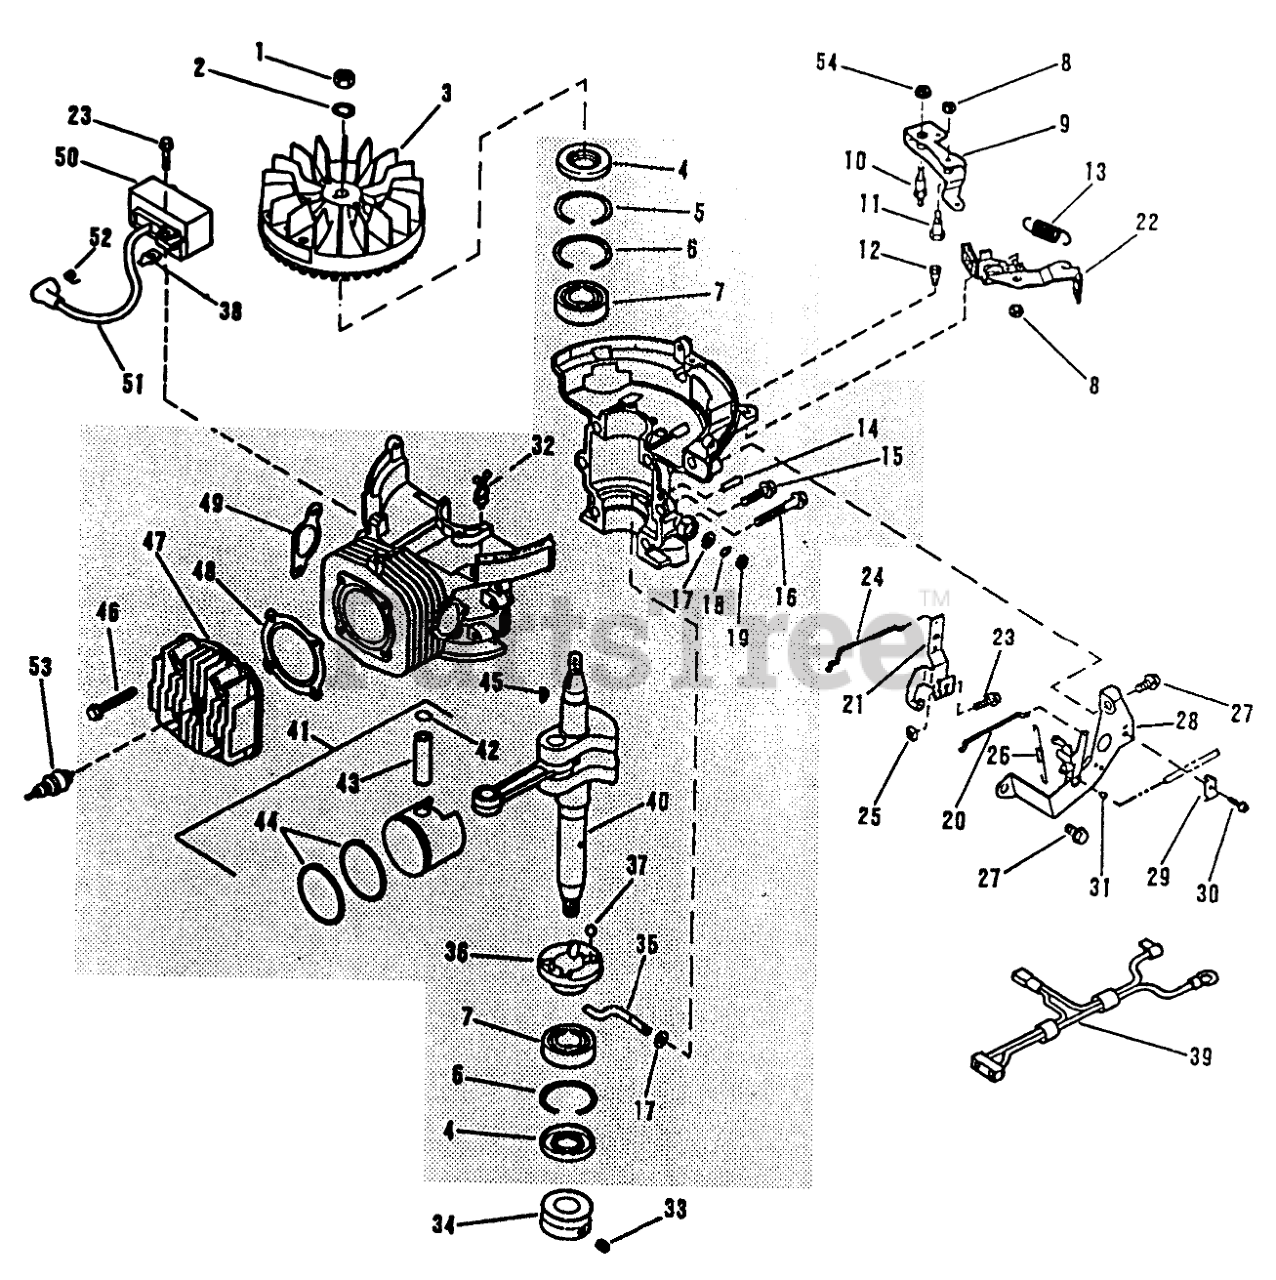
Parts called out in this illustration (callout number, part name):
2	WASHER-LOCK
3	F/WHEEL ALUM SM
4	SEAL - OIL SM
5	RING-RETAINER SM
6	RING RET. SM
7	BEARING-BALL SM
8	LOCKNUT E
9	ACT.BRAKE LVR. SM
10	STUD-SHOULDER SM
11	BOLT-SHOULDER SM
12	BOLT-SHOULDER SM
13	SPRING-BRAKE
14	PIN, TAPER SM
15	SCREW-H.W.HD. F
16	SCREW-HEX W.H. SM
17	WASHER-FLAT SM
18	RING-RETAINING
19	SEAL - OIL SM
20	ROD - CHOKE SM
21	GOV CTL LEVER SM
22	BRAKE & SWITCH S
23	SCREW
24	ROD-THROTTLE SM
25	NUT SM
26	SPRING-GOV. SM
27	SCREW HEX WASH SM
28	GOVNR BRKT SM
29	CLAMP SM
30	SCREW-CLAMP SM
31	Retainer-Throttle Wire
32	WIRE TIE SM
33	SCREW-SET
34	PULLEY - ENGINE S
35	Governor Arm
36	Governor Ramp
37	BALL-GOVERNOR SM
38	TERMINAL M
39	WIRE HARN AY SM
40	C/SHAFT&C.ROD SM
41	PISTON&RING AY. S
42	RING-RETAINER SM
43	WRIST PIN SM
44	RING SET S
46	SCREW
47	CYLINDER HEAD SM
48	GASKET-HEAD SM
49	GASKET - EXH SM
50	CD Ignition
51	HI-TENS.LEAD SM
53	Spark Plug
54	Hex Flang Nut
